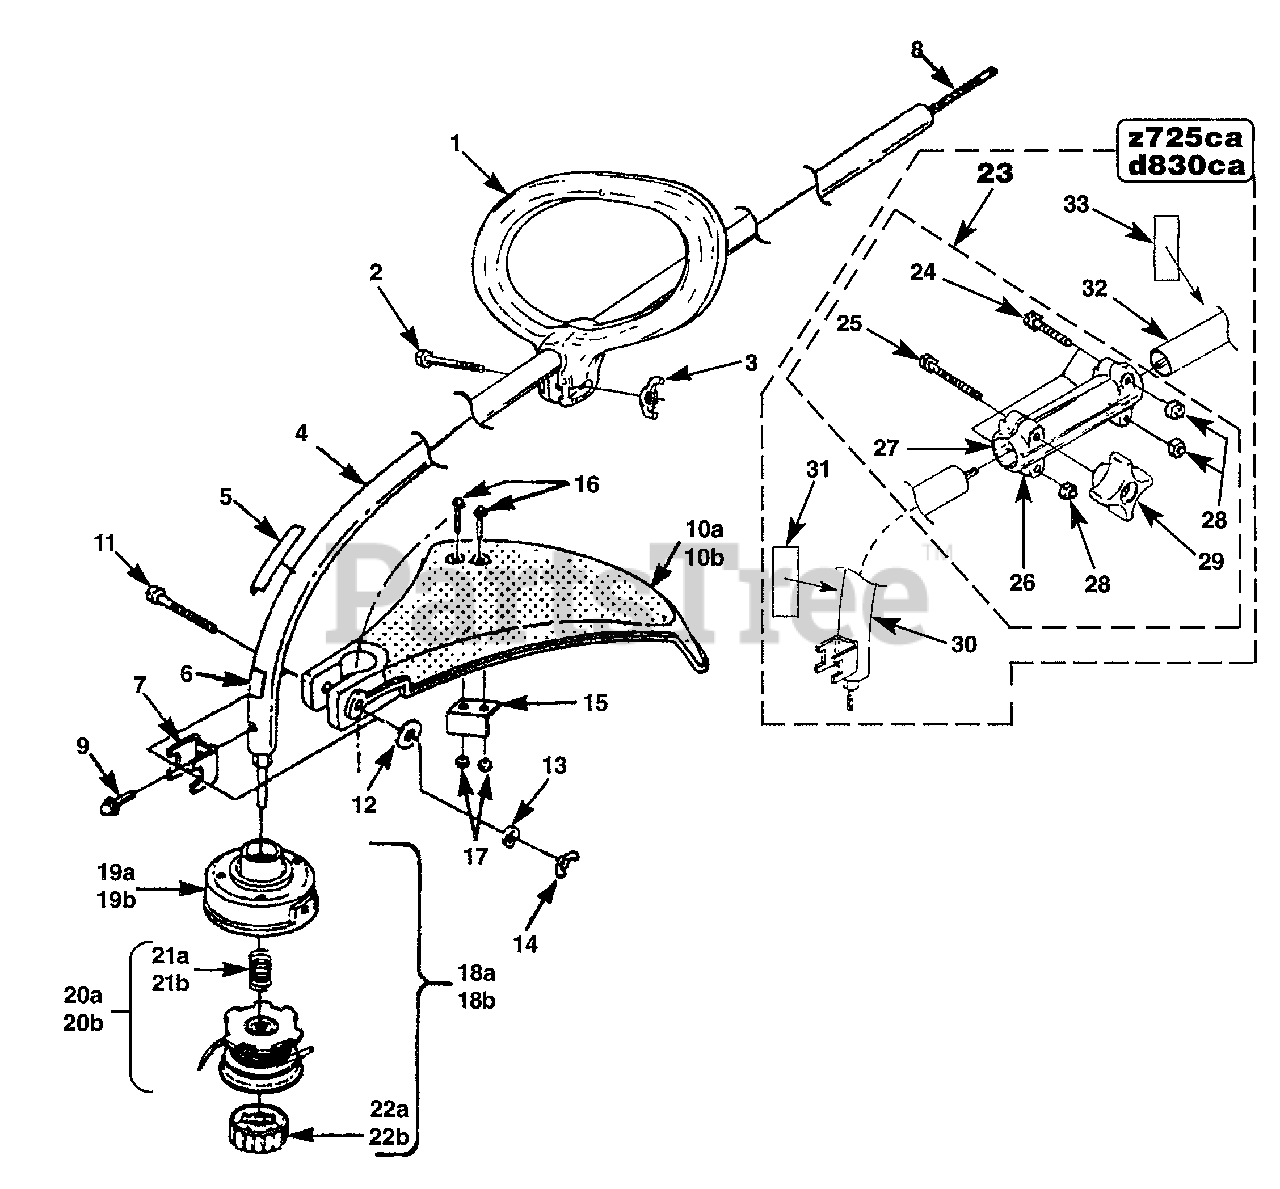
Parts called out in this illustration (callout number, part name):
1	FRONT HANDLE ("D")
2	SCREW-Cap Hex Hd. (10-24 X 2")
3	NUT-Wing (10-24)
4	HOUSING-Drive Shaft
5	DECAL-Starting Inst.
6	DECAL-Warning
7	CLAMP
8	SHAFT-Flexible
9	SCREW-Drilling (#10 X 1/2")
10A	DEFLECTOR & BLADE KIT (55 Degree)
10B	DEFLECTOR & BLADE (100 Degree)
11	SCREW-Cap Hex Hd. (1/4-20 X 2")
12	WASHER-Flat (1/4")
13	WASHER-Lock (1/4")
14	NUT-Wing (10-24)
15	BLADE-Cut-Off Kit
16	SCREW-Mech. Hex Hd. (10-24 X 7/8")
17	NUT-Hex (10-24)
18A	STRING HEAD-Complete (.080" Line)
18B	STRINGHEAD COMPLETE (.095" Line)
19A	HOUSING & EYELET (Dual Line)
19B	HOUSING & EYELET (Dual Line)
20A	SPOOL & STRING & SPRING (.080" Line)
20B	SPOOL & STRING & SPRING (.095" Line)
21A	SPRING-Compression
21B	SPRING-Compression
22A	RETAINER-Spool (R.H. Thread, Black)
22B	RETAINER-Spool (R.H. Thread, Black)
23	COUPLER ASSEMBLY
24	BOLT-Hex Hd.
25	SCREW-Cap Hex (1/4-20 x 2")
26	SPLIT BOOM (L.H.)
27	SPLIT BOOM (R.H.)
28	NUT-Hex (1/4-20)
29	KNOB
30	DRIVE SHAFT HOUSING-(Lower)
31	DECAL-Warning
32	DRIVE SHAFT HOUSING-(Upper)
33	DECAL-Start Instructions
